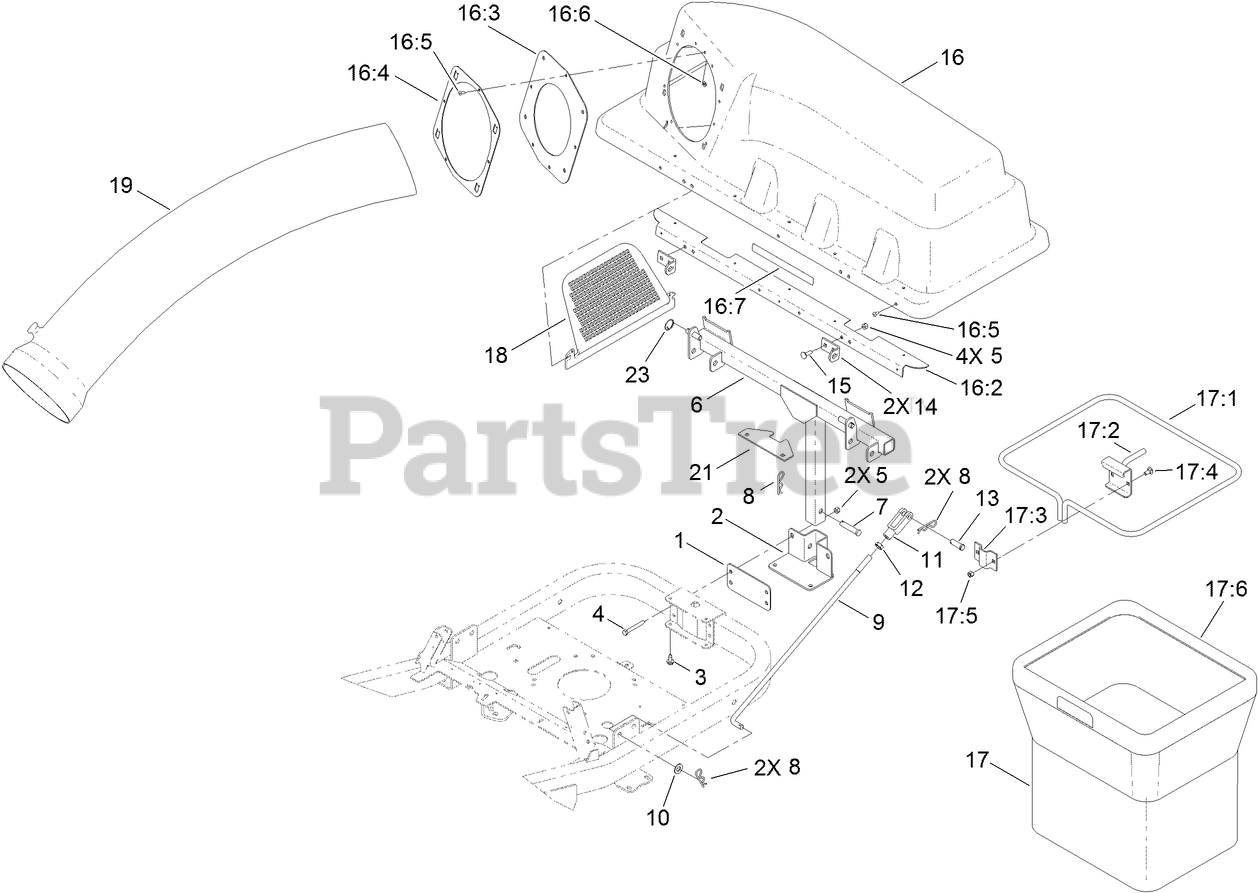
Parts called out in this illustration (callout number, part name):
2	SUPPORT-BAGGER
3	SCREW-HWHTF
4	SCREW-HH
5	NUT-LOCK, NI
6	FRAME-PIVOT
7	PIN-CLEVIS
8	PIN-HAIR
9	ROD-BAGGER
10	WASHER-FLAT
11	CLEVIS
12	NUT-JAM
13	PIN-CLEVIS
14	BRACKET-PIVOT, HOPPER
15	BOLT-CARR
16	BAGGER TOP ASM
16:2	STIFFENER-BAGGER TOP
16:3	GASKET
16:4	RING-RETAINER
16:5	RIVET-BLIND
16:6	WASHER-FLAT
16:7	DECAL-CAUTION, BAGGER
17	BAG ASM
17:1	FRAME-BAG
17:4	BOLT-CARR
17:5	NUT-LOCK, NI
17:6	BAG
18	SCREEN-BAGGER
19	TUBE-BAGGER
21	PLATE-SPACER
23	PIN-COTTER, CIRCULAR
